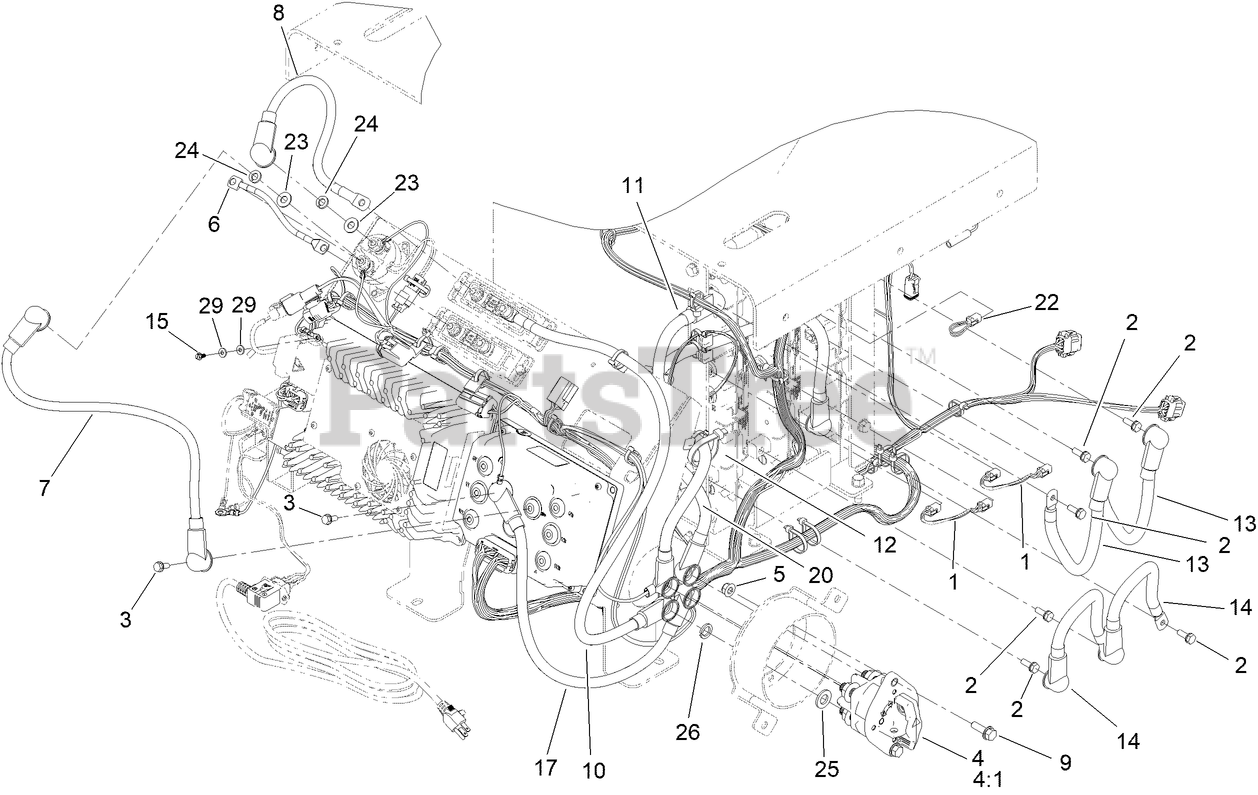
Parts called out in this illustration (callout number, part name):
1	HARNESS-WIRE, DATA INTERFACE
2	SCREW-SEMS
3	SCREW-SEMS
4	SWITCH-DISCONNECT
4:1	NUT-HF
5	NUT-HF, NI
6	CABLE-BATTERY, RD ASM
7	CABLE-BATTERY,RD ASM
8	CABLE-BATTERY,RD ASM
9	SCREW-HHF
10	CABLE-BATTERY, RD ASM
11	CABLE-BATTERY, RD ASM
12	TIE-CABLE
13	CABLE-BATTERY,RD ASM
14	CABLE-BATTERY,BK ASM
15	SCREW-GROUND
17	CABLE-BATTERY, BK ASM
20	CABLE-BATTERY, BK ASM
22	HARNESS-WIRE, CAN TERMINATOR
23	WASHER
24	WASHER-LOCK
25	WASHER-FLAT
26	SPLIT LOCK WASHER,1/2,ST/ST,18-8
29	WASHER-FLAT
